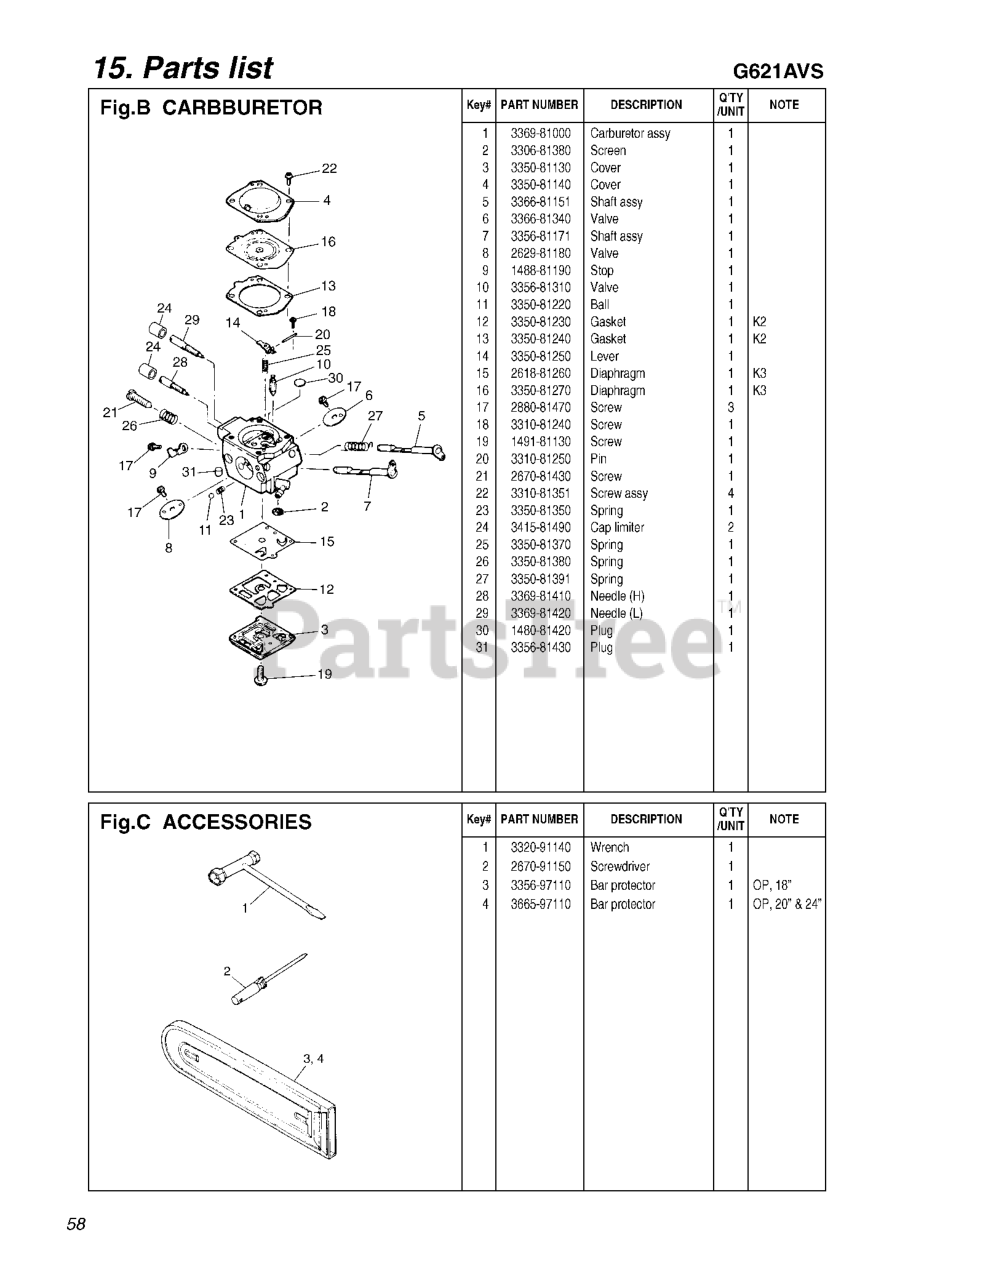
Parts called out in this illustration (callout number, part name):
2	SCREEN
10	VALVE INLET
15	DIAPHRAGM
16	DIAPHRAGM
17	SCREW
19	SCREW Z149181130
22	SCREW ASSY
23	CHOKE SPRING
24	CAP
A3	PROTECTOR
A4	PROTECTOR
